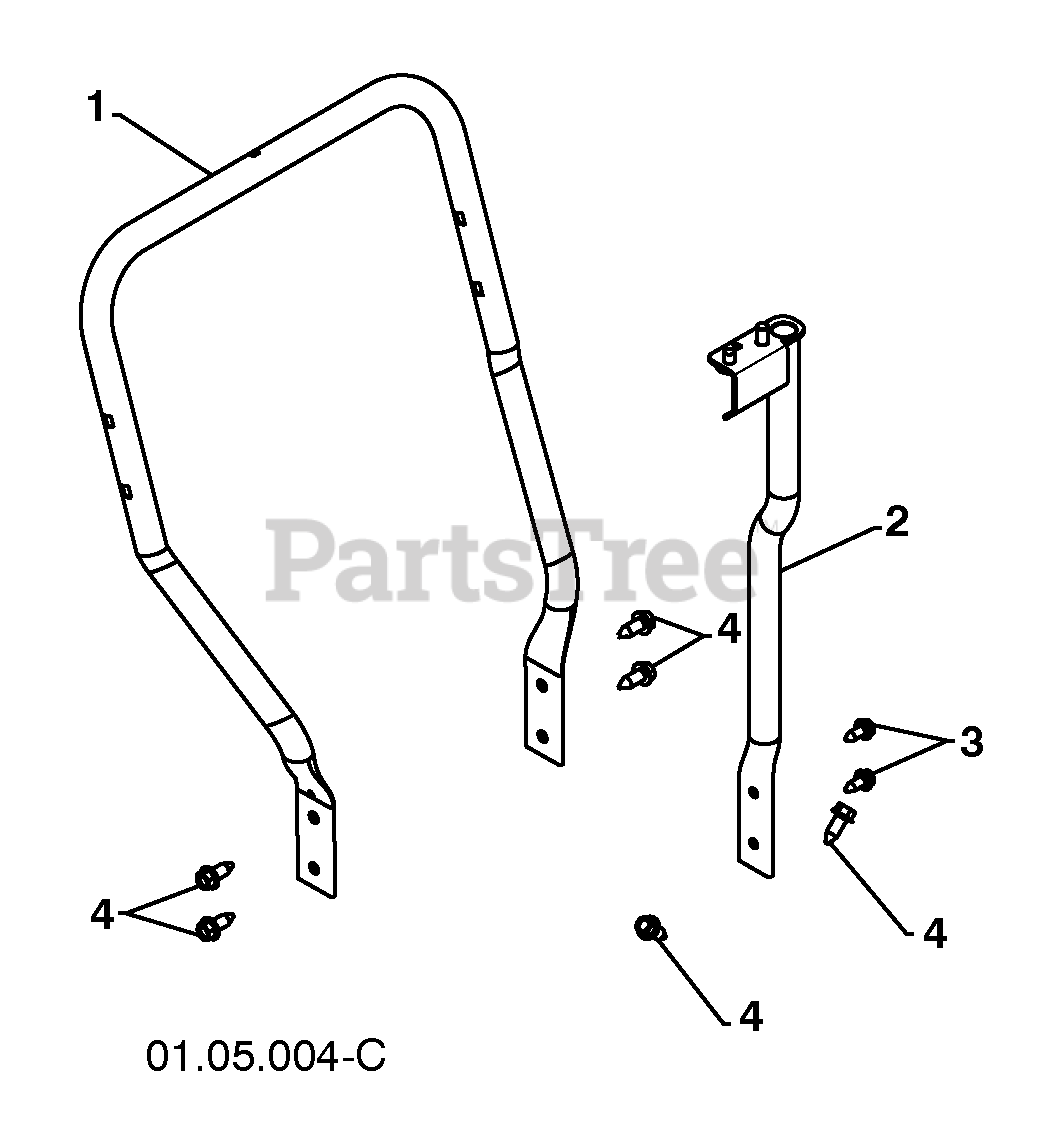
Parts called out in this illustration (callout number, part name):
1	LOWER TUBE
3	BOLT 5/16-18 X .750
4	SCREW 3/8-16 X 1.00
